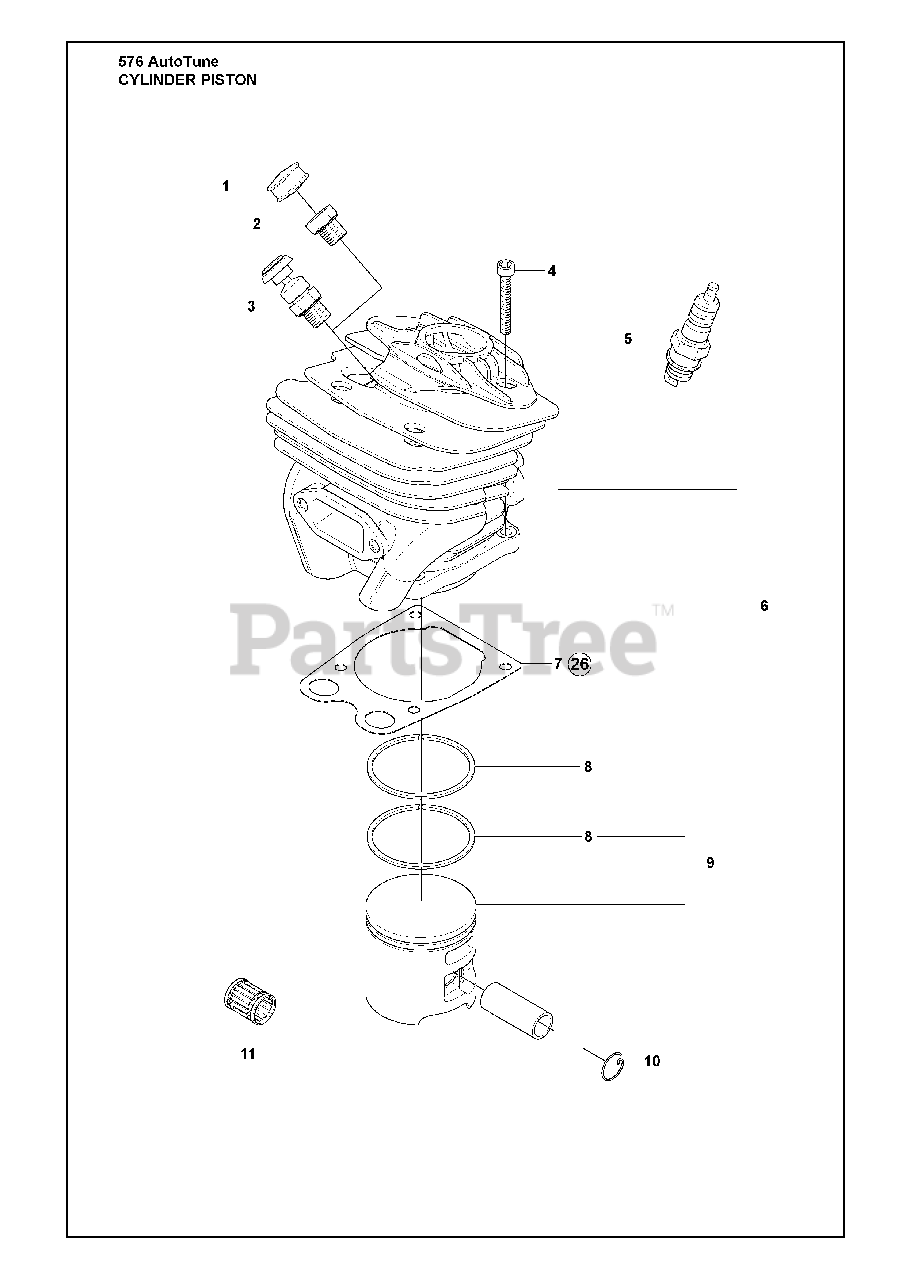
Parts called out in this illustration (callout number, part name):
2	CYLINDER PLUG
3	VALVE
4	SCREW MC6S 5X25
5	BPMR7A NGK SPARK PLUG
6	CYLINDER ASSY
8	%PISTON RING
9	PISTON ASSY
10	WRIST PIN CLIP
11	SUPPORT BUSHING
26	GASKET KIT
